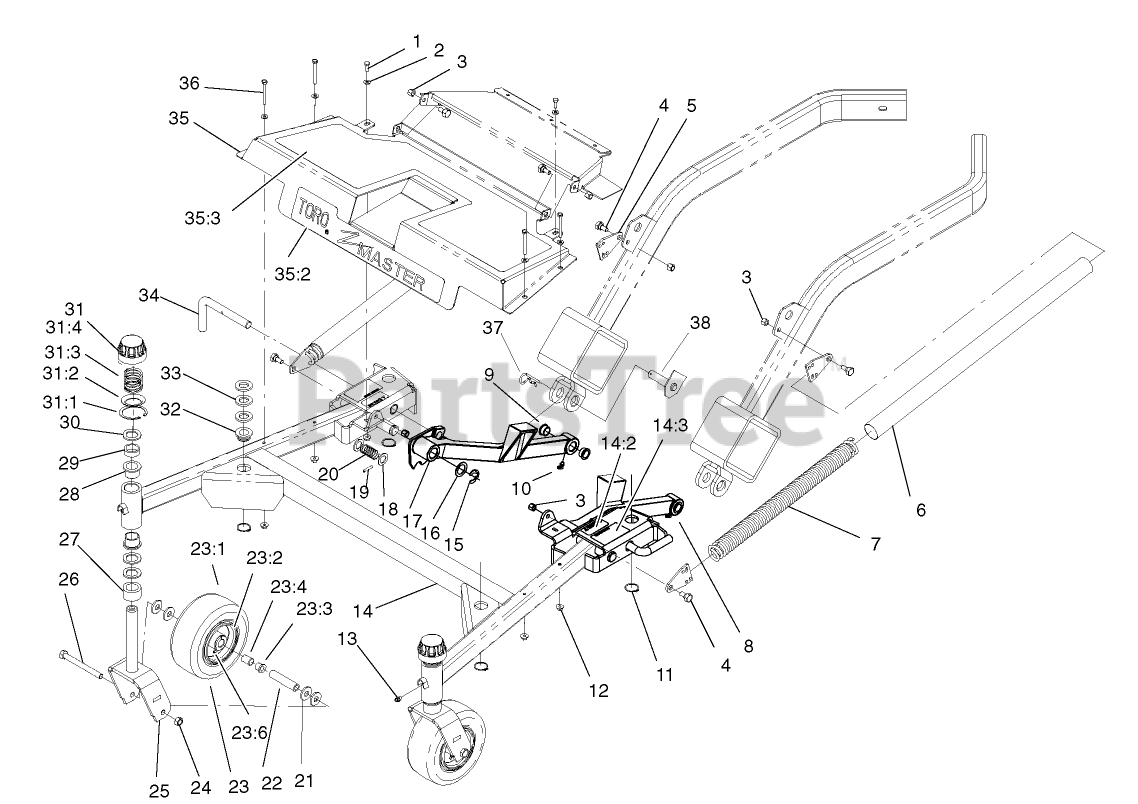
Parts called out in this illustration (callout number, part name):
1	SCREW-HH
2	WASHER-FLAT
3	NUT-LOCK, NI
4	BOLT-SHOULDER
5	PLATE-END, SPRING
6	COVER-SPRING
7	SPRING-EXTENSION
8	Casting-Lift Arm, LH
9	BEARING-FLANGE
10	FITTING-GREASE
11	RING-RETAINING
12	NUT-HF
13	FITTING-GREASE
14	CARRIER FRAME ASM
14:2	DECAL-WARNING
14:3	DECAL-ADJUSTMENT, CUTTING HEIGHT
15	RING-RETAINING
16	Washer
17	Casting-Lift Arm, RH
18	WASHER
19	PIN-ROLL
20	SPRING-COMPRESSION
21	WASHER-FLAT
22	SPANNER-TIRE
23	CASTOR WHEEL ASM
23:2	RIM ASM
23:3	BEARING-OUTSIDE
23:4	BEARING-ROLLER
23:6	FITTING-LUBE, 45 DEG
24	NUT-HEX
25	CASTOR FORK ASM
26	SCREW-HH
27	SPACER-CASTOR
28	BUSHING
29	SPACER
30	WASHER-THRUST
31	HOC CAP ASM
31:1	RING-RETAINING
31:2	WASHER-CAP
31:3	SPRING-COMPRESSION
31:4	CAP-HOC
32	BUSHING-DECK
33	WASHER-FLAT
34	PIN-PIVOT
35	FOOTREST ASM
35:3	PAD-FOOTREST
36	SCREW-HH
37	PIN-HAIR
38	PIVOT PIN ASM
